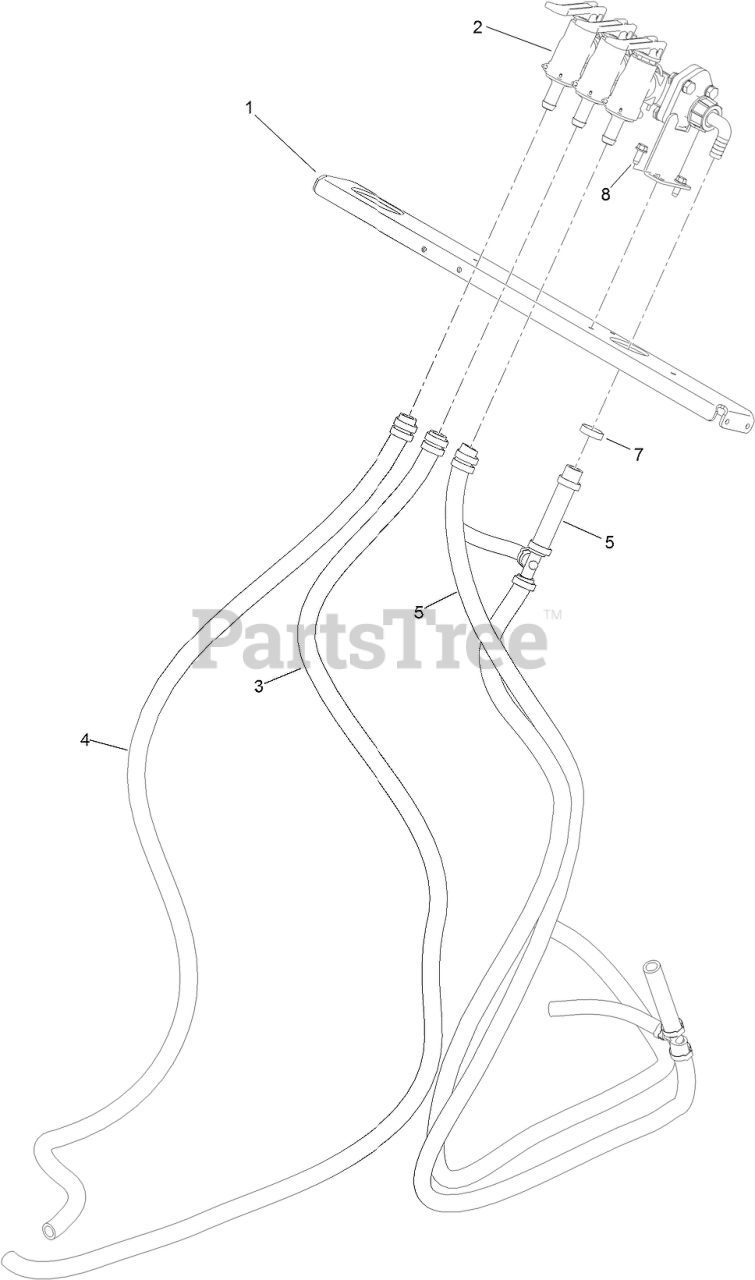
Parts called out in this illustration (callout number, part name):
1	Crossmember-Column
2	Manifold-Valve, Control
3	HOSE-WATER
4	HOSE-WATER
5	Hose ASM
8	SCREW-HWH
